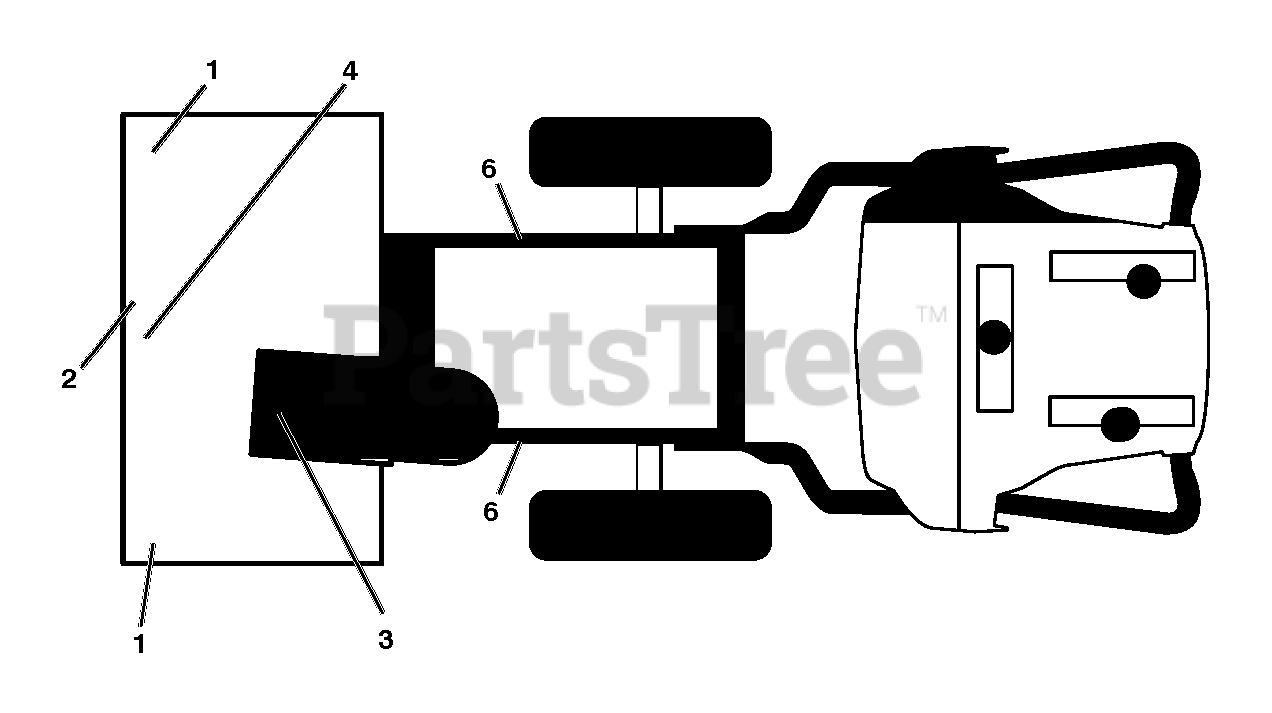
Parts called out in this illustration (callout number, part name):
1	DECAL.AUGER.SAFETY.
2	DECAL.AUGER HSG.HUSQ.ST 224
3	DECAL.CHUTE.SAFETY.EU/SC.17
4	DECAL.AUGER."
6	DECAL.BELT.GUARD.
